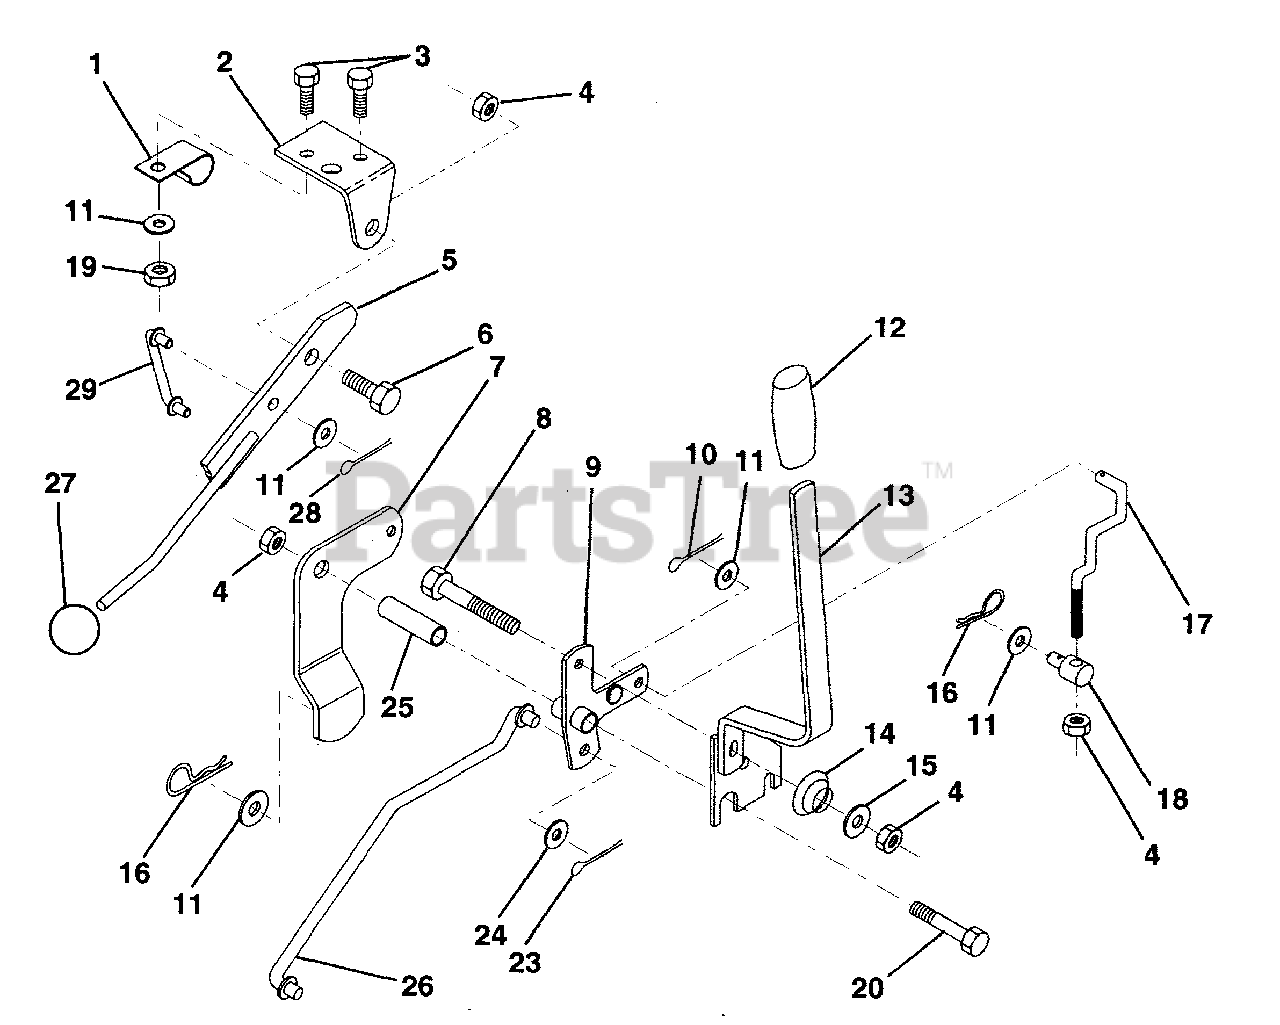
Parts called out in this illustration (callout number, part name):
1	Clip, Insulated
2	Bracket, Mower Clutch
3	Bolt, Hex Head, Fin. 1/4-20 UNC x 1/2 Grade 5
4	Nut, Crown lock 3/8-16 UNC
5	Clutch Lever Assembly
6	Bolt, Shoulder
7	Assembly, Mower Clutch Arm
8	Bolt, Hex 3/8-16 UNC x 2-1/4
9	Lift Bracket Assembly
10	Pin, Cotter 1/8 x 3/4
11	Washer 13/32 x 13/16 x 16 Ga.
12	Grip, Handle
13	Assembly, Lift Handle
14	Spring, Compression
15	Washer 13/32 x 3/4 x 12 Gauge
16	Retainer, Spring
17	Link, Front Lift
18	Trunnion, Threaded 3/8-16
19	Nut, Crownlock 1/4-20
20	Bolt, Hex Head, Fin. 3/8-16 UNC x 2-3/4
23	Pin, Cotter 1/8 x 1
24	Washer 17/32 x 1 x 16 Gauge
25	Tube, Spacer
26	Rod, Mower Lift
28	Pin, Cotter 3/32 x 3/4
29	Link, Mower Clutch
